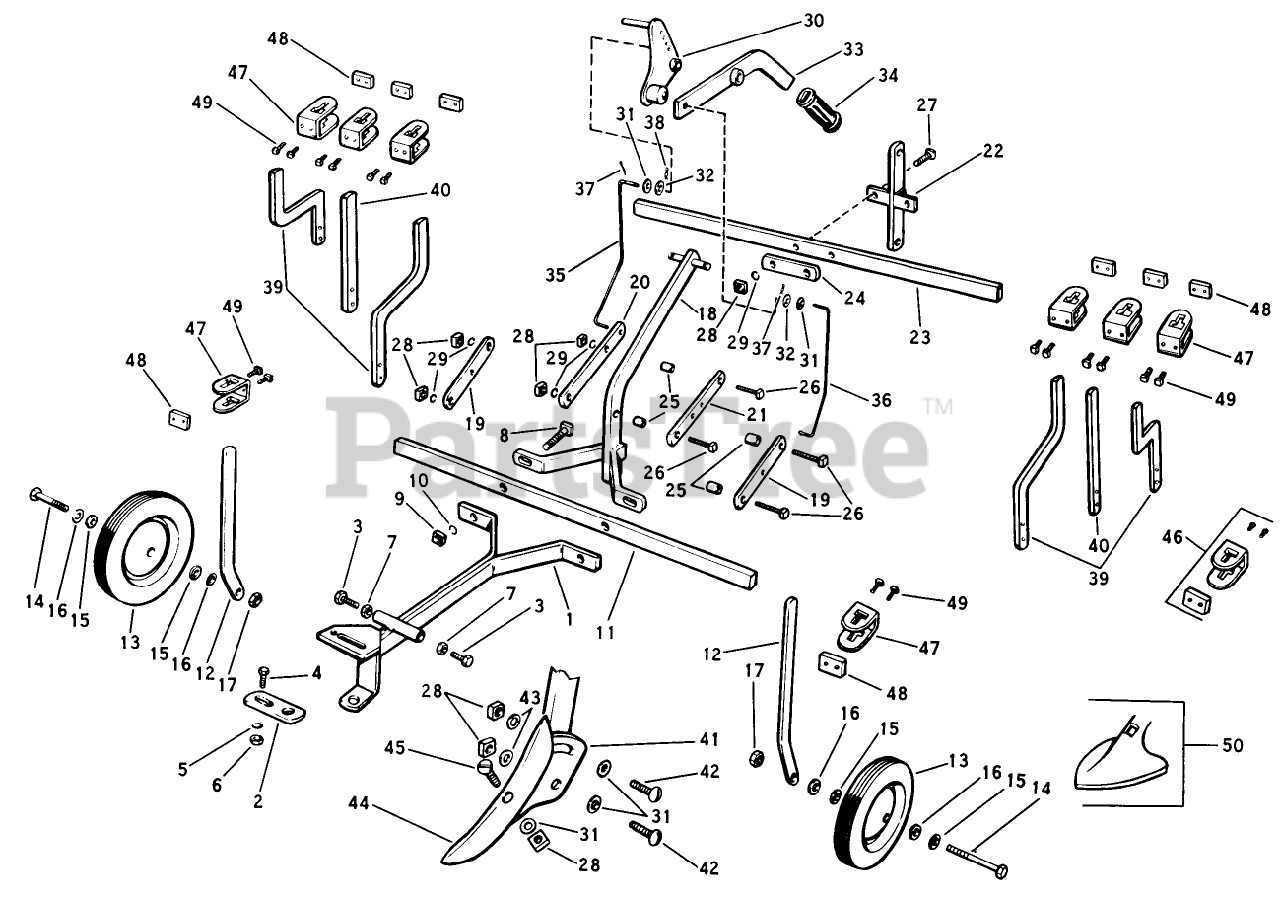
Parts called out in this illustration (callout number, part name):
1	Drawbar Assembly
3	Capscrew 3/8-16 x 1-1/4 Lg.
4	Capscrew 5/16-18 x 3/4 Lg.
5	BAR-LIFT LINK *R
8	Square Head Machine Bolt 1/2-13 x 1-3/4 Lg.
10	Lockwasher 1/2
14	Hex Head Axle Bolt 1/2-13 x 4 Lg.
15	Rubber Washer
16	Washer 1/2 SAE
18	Operating Lever Support Assembly
19	ORDER 103285 & 103286
22	Rear Pivot Bar Assembly
25	Spacer Sleeve
26	Square Head Machine Bolt 3/8-16 x 1-1/2 Lg.
28	Square Nut 3/8-16
30	Operating Lever Assembly
33	Lift Lever Assembly
37	Cotter Pin 3/32 x 1 Lg.
40	Shovel Support, Straight
41	Adjusting Tool Holder Assembly
42	Carr. Bolt 3/8-16 x 1-1/2 Lg.
43	Washer 7/16
46	Clamp Assembly
48	Clamp Plate
